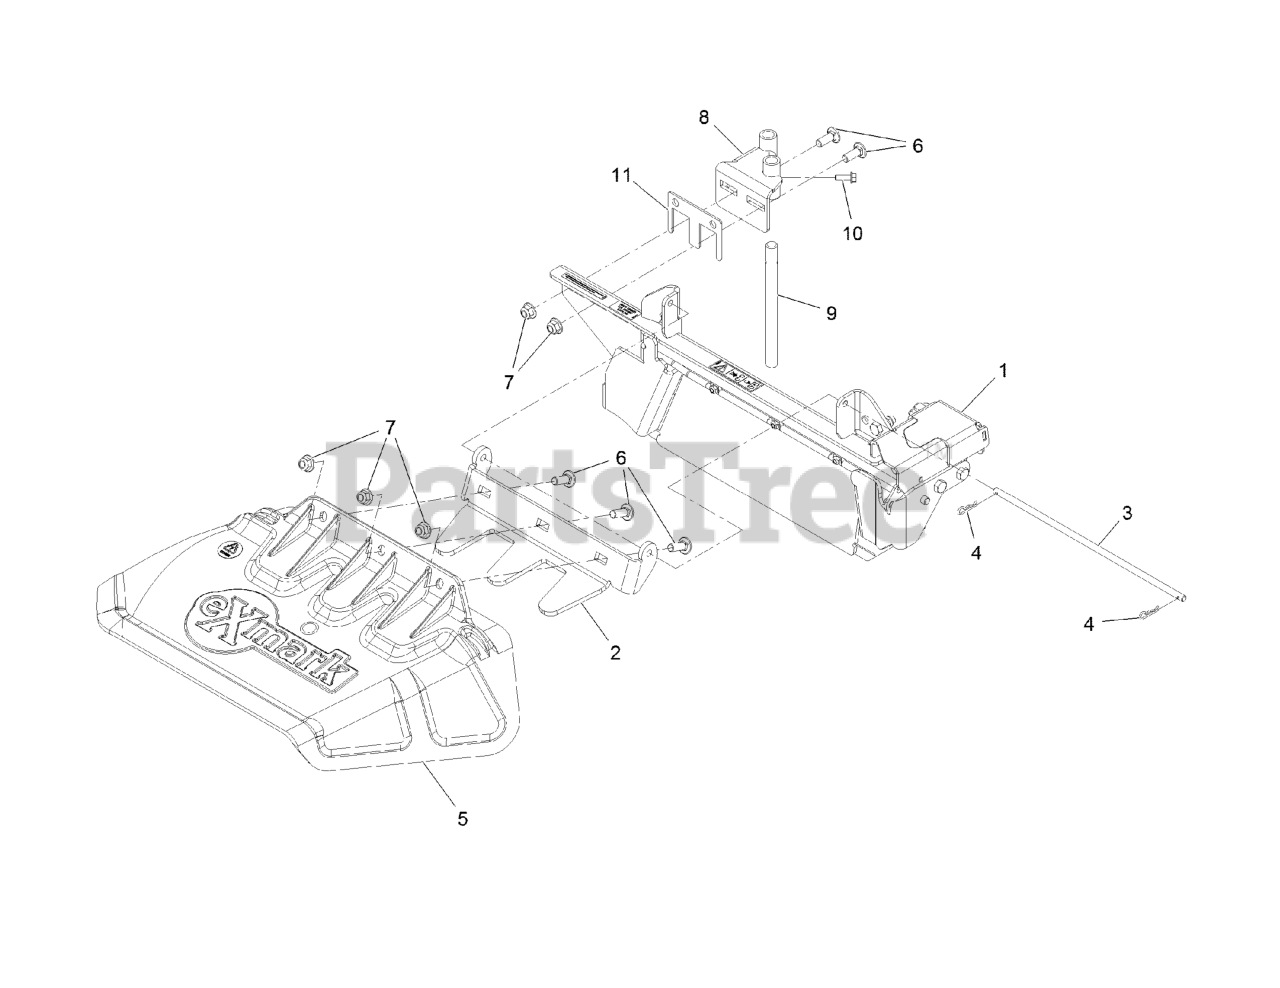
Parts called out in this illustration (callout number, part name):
1	ASM, OCD GATE
2	MOUNT, DISCHARGE CHUTE
3	PIN,CHUTE
4	PIN-COTTER
5	CHUTE,DISCHARGE
6	SCREW-CARR
7	NUT-HF, NI
8	WELDMENT, OCD MOUNT
9	PIN-MOUNT, OCD
10	SCREW-HHF
11	SHIM-OCDWB
